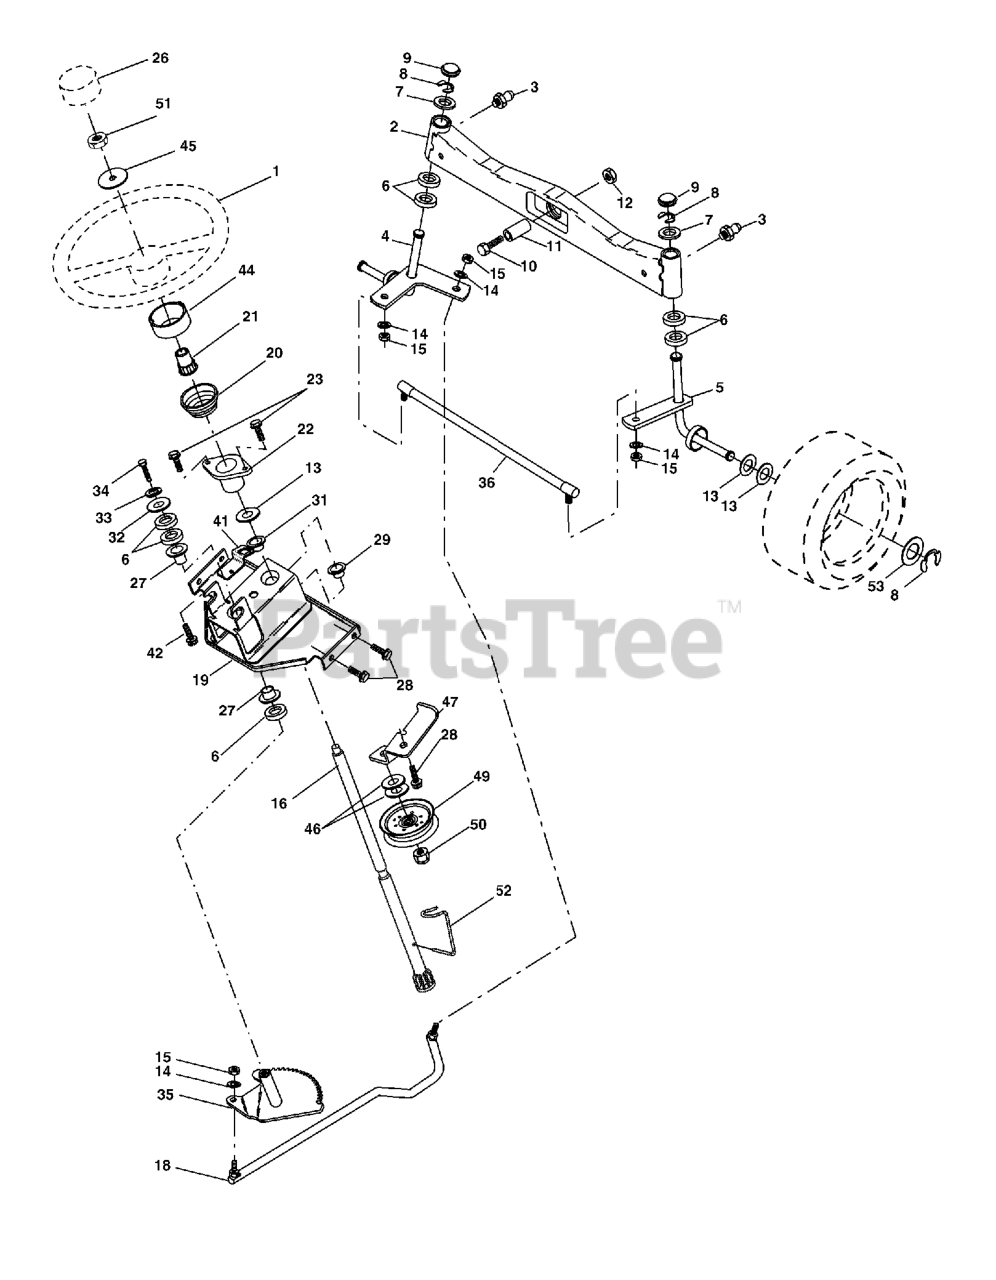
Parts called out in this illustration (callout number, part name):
1	STEERING WHEEL
2	AXLE.FRONT.CAST.MACHINE.W/ZERK
3	FITTING.GREASE.TAPERED
4	SPINDLE ASSY LH
5	SPINDLE ASM RH
6	THRUST WASHER
7	WASHER
8	RING CLIP
9	CAP.SPINDLE.BLACK
10	Bolt, Hex 5/8 -11 x 2 - 3/4 Gr. 5
11	TUBE, PIVOT AXLE
12	NUT-LOC,FLANGE LT
13	WASHER
14	WASHER, LOCK 3/8
15	NUT CROWNLOCK 3/8-24
16	SHAFT ASM, STEERING
18	DRAGLINK, BALL JOINT (3SPG1401
19	SUPPORT ASM., STEERING VGT
20	BOOT, STEERING
21	STEERING WHEEL ADAPTOR
22	BUSHING, STRG. BLK
23	SCREW.TT.#10-32X.5.3/8.FLANGE
26	CAP.WHEEL.STEERING.GREY
27	BRNG T
28	SCREW, 3/8-16X3/4
29	BEARING-FLANGE GT
31	BUSHING.NYLINER.
32	WASHER
33	WASHER.LOCK.HVY.HLCL.SPR.5/16
34	BOLT.FIN.HEX.5/16-18X3/4
35	GEAR.ASM.SECTOR.PITMAN
36	ROD.TIE.NON-ADJUSTABLE
41	BRACKET INTERLOCK
42	Screw 5/16-18 x 1/2 Hex, Self Tapping 5/16-18 x 1/2
44	EXTENSION STEERING PREMIUM
45	Washer 9/16 ID x 1 1/2 OD 11 Ga. Zin
46	WASHER PM
47	BRKT.ASM.IDLER.STATIONERY
49	PULLEY.IDLER.FLAT.46.PR.DR.
50	NUT LOCK FLG 3/8-16 UNC
51	NUT.HEX.1/2-20
52	CLIP.STEERING
53	WASHER.HARDENED
